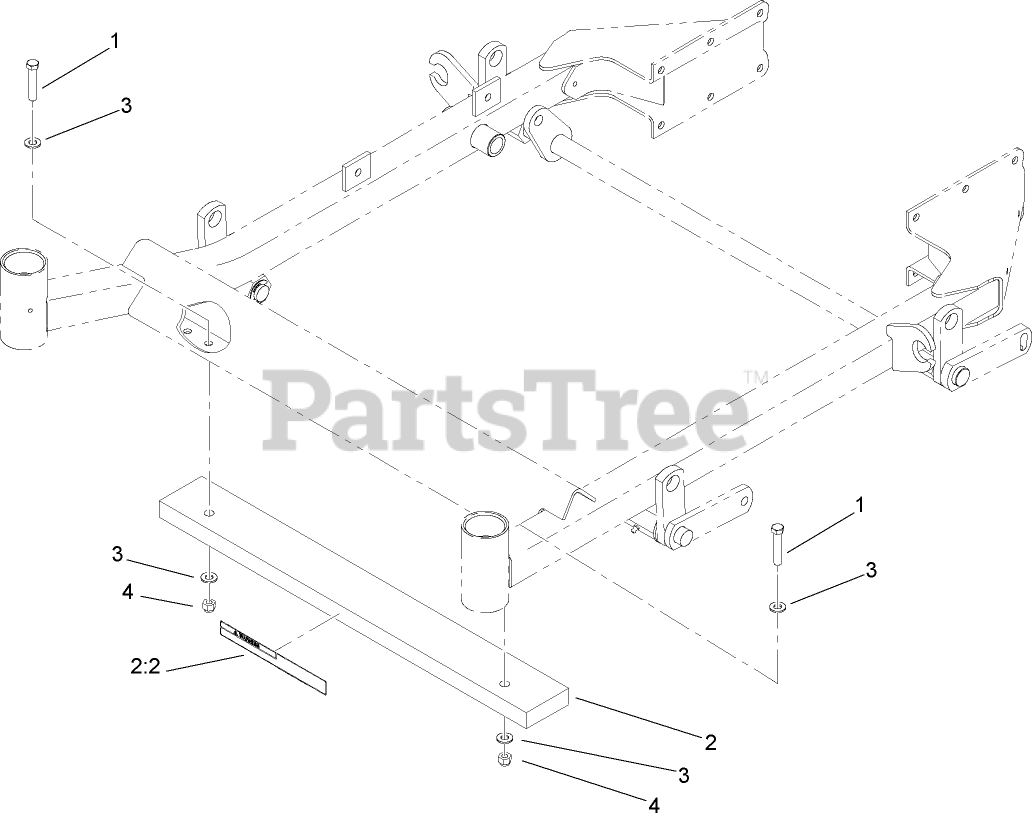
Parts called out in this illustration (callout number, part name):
1	SCREW-HH
2	WEIGHT
2:2	DECAL-WARNING, COUNTER WEIGHT
3	WASHER-FLAT
4	NUT-LOCK, NI
